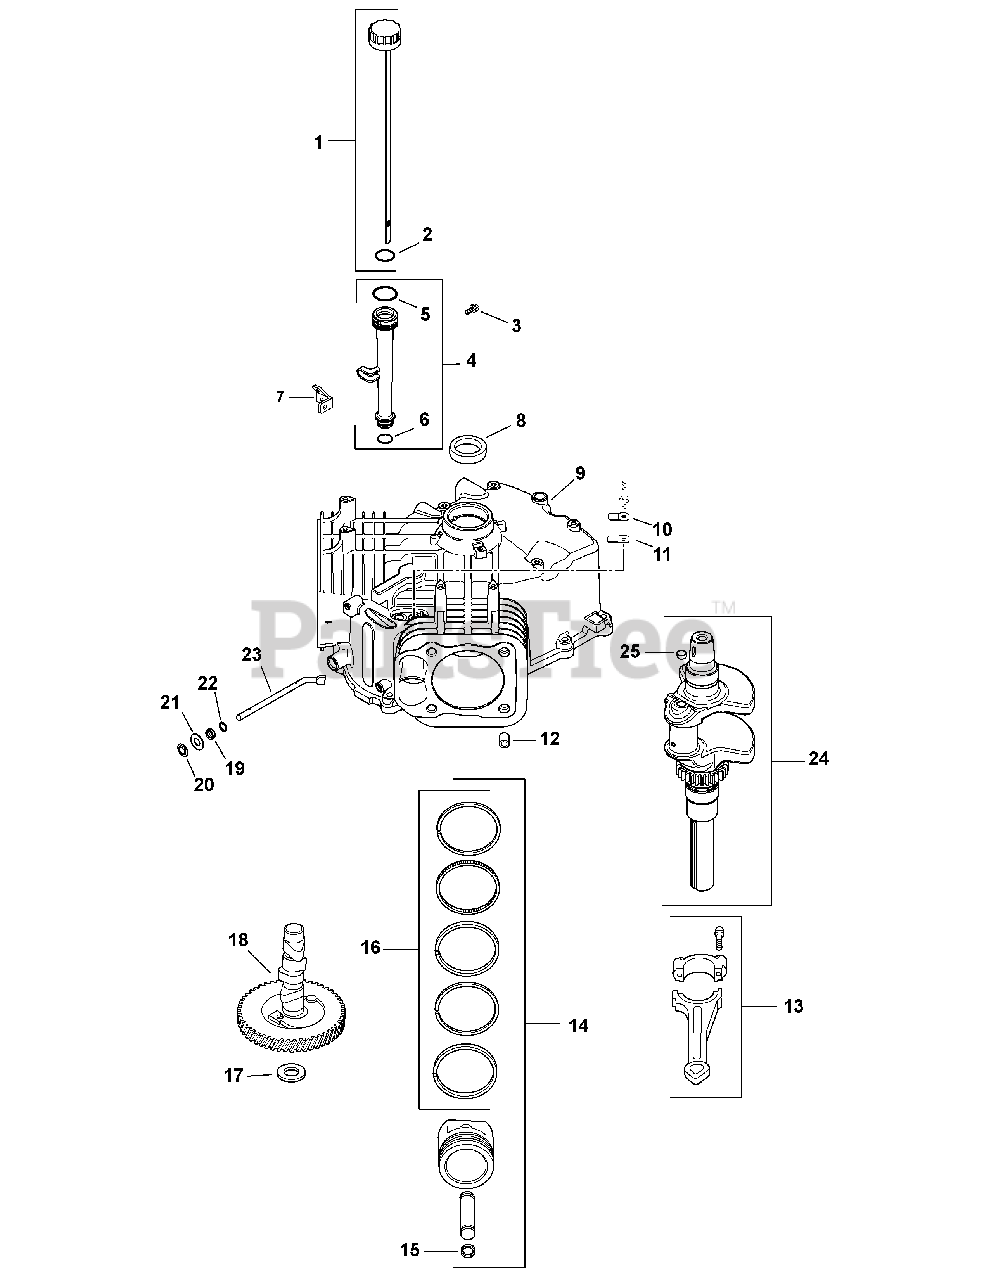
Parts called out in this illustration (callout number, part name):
1	Dipstick Assembly (Incl. Ref.2)
2	O-Ring, Dipstick
3	Screw, Flnge Thrd. Frmng M5 x .8 x 13
4	Kit, Oil Fill Tube (Incl. Ref. 5,6)
5	O-ring, Upper Fill Tube
6	O-ring, Lower Fill Tube
7	Bracket, Fill Tube
8	Seal, Oil
9	Crankcase - Use Short Block
9	Short Block
10	Retainer, Breather Reed
11	Reed, Breather
12	Pin, Locating
13	Connecting Rod (Std.)
14	Kit, Piston w/Ring Set (Std.)
14	Kit, Piston w/Ring Set (.25)
14	Kit, Piston w/Ring Set (.08)
15	Retainer, Piston Pin
16	Ring Set (Std. & .08)
16	Ring Set (.25)
17	Shim, Camshaft (White .028)
17	Shim, Camshaft (Blue .03)
17	Shim, Camshaft (Red .032)
17	Shim, Camshaft (Yellow .034)
17	Shim, Camshaft (Green .036)
17	Shim, Camshaft (Gray .038)
17	Shim, Camshaft (Black .04)
18	Kit, Camshaft
19	Seal, Governor Cross Shaft
20	Retaining Ring
21	Washer, Flat, 9mm
22	Washer, Flat, 11/32
23	Shaft, Governor Cross
24	Crankshaft (Incl. Ref. 25)
